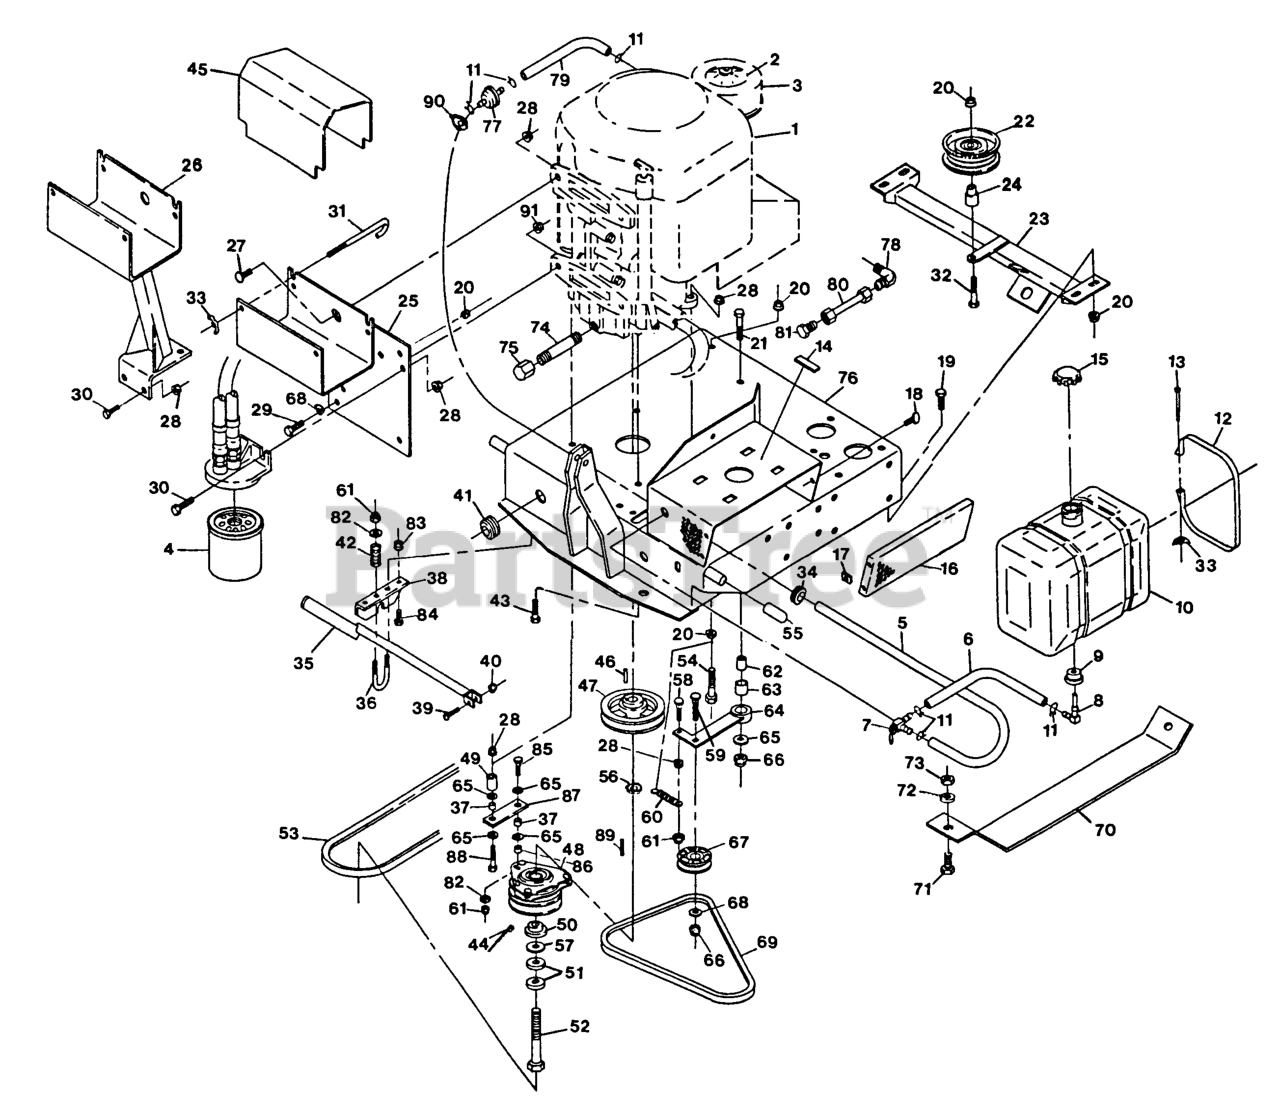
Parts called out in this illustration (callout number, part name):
1	Engine - 18 Hp
2	Air Filter
3	Foam Precleaner
4	Oil Filter
8	ELBOW-TANK, FUEL
13	SCRW,MACH CRPH
14	PAD,PLASTIC TANK
15	CAP-FUEL
17	NUT,RETNR UTYP 1/4-20
18	SCREW,REGTHMB,
23	WLD,CROSSMEMBER
24	BUSHING,IDLER
31	BOLT - HOLD DOWN
33	WINGNUT
34	GROMMET
37	SPACER,CLUTCH ANCHOR
40	NUT-LOCK, HH
41	GROMMET
42	SPRING-COMPRESSION
44	TIE-PLASTIC
46	KEY,MACH 1/4X1/4X2-5/8
47	SHEAVE,4.25 OD A
51	WASHER-SPRING
53	BELT-DK DR FMD-60/TR
55	GRIP-LEVER, DRIVE
60	SPRING,EXTENSION
62	BUSHING,STEEL
63	BUSHING,IDLER ARM
64	WLD,IDLER ARM HYDRO
67	IDLER,PULLEY
69	BELT,A TRANS DRIVE
70	PLATE-SKID
79	HOSE-FUEL
89	KEY
90	CLAMP-HOSE
